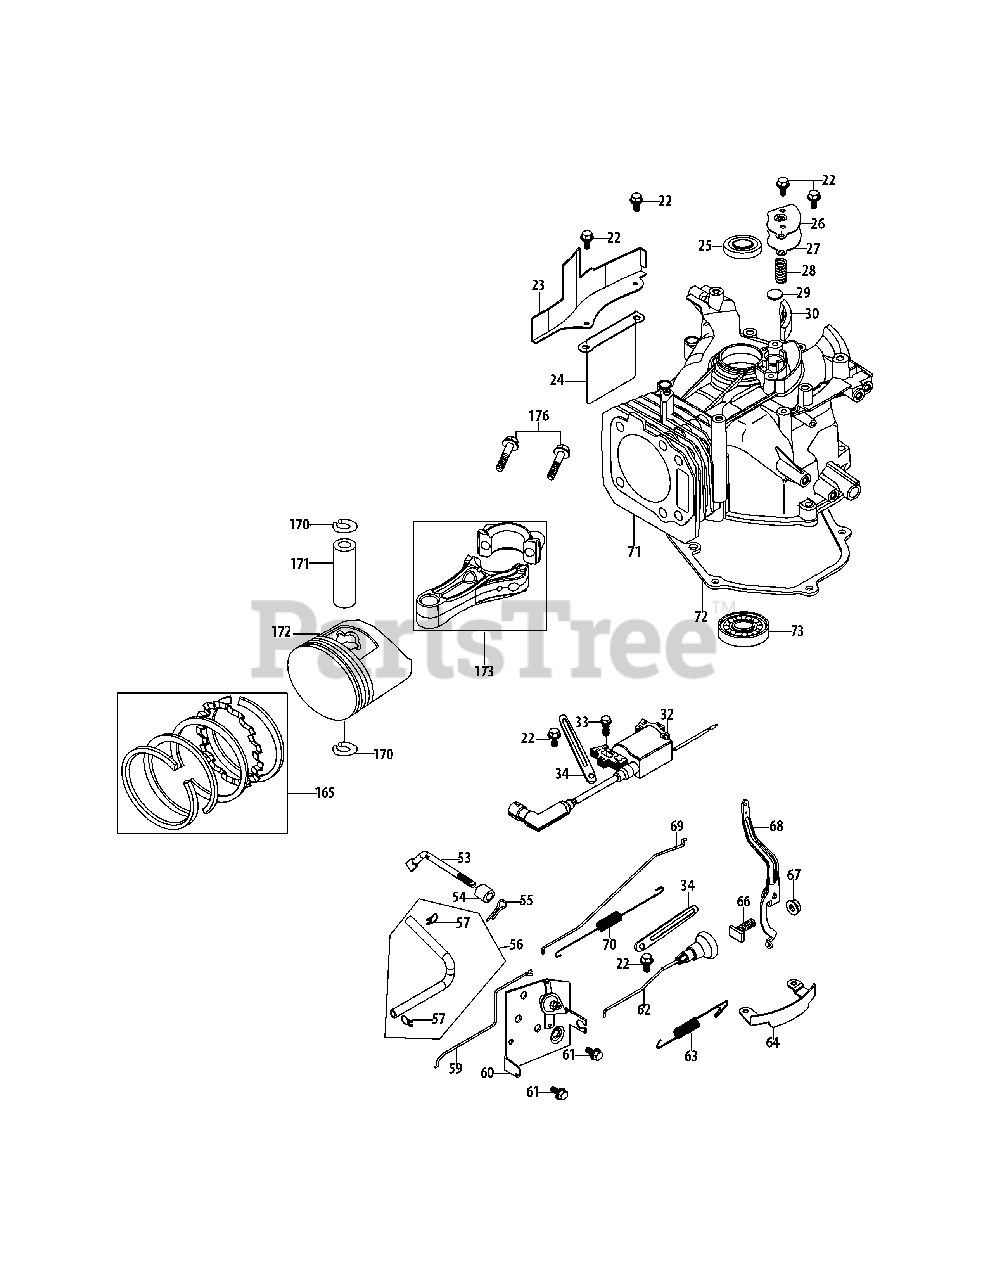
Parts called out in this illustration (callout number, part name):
22	Bolt M6X14 Multi-Purpose
23	Engine Brake Cover Plate
24	Label Bracket
25	Upper Crankshaft Seal
26	Breather Cover Plate
27	Breather Gasket
28	Breather Spring
29	Breather Valve
30	Mesh Screen
32	Ignition Coil Assembly
33	Bolt M6X18 P70 Ign. Coil
34	Flexible Clamp
53	Governor Arm Shaft
54	Governor Seal
55	Governor Shaft Cotter Pin
56	Breather Hose Assembly
57	Breather Hose Clamp
59	Choke Linkage
60	Component Bracket
61	Bolt M6X12 Component/Vrbl Spd Brkt
62	Choke Control
63	Governor Spring
64	Governor Arm Guard
66	Governor Arm Bolt
67	Governor Arm Nut M6
68	Governor Arm
69	Throttle Linkage
70	Throttle Linkage Spring
71	Short Block Assembly
72	Crankcase Cover Gasket
73	Main Bearing
165	Piston Ring Set
170	Piston Pin Snap Ring
171	Piston Pin
172	Piston
173	Connecting Rod Assembly
176	Connecting Rod Bolt
